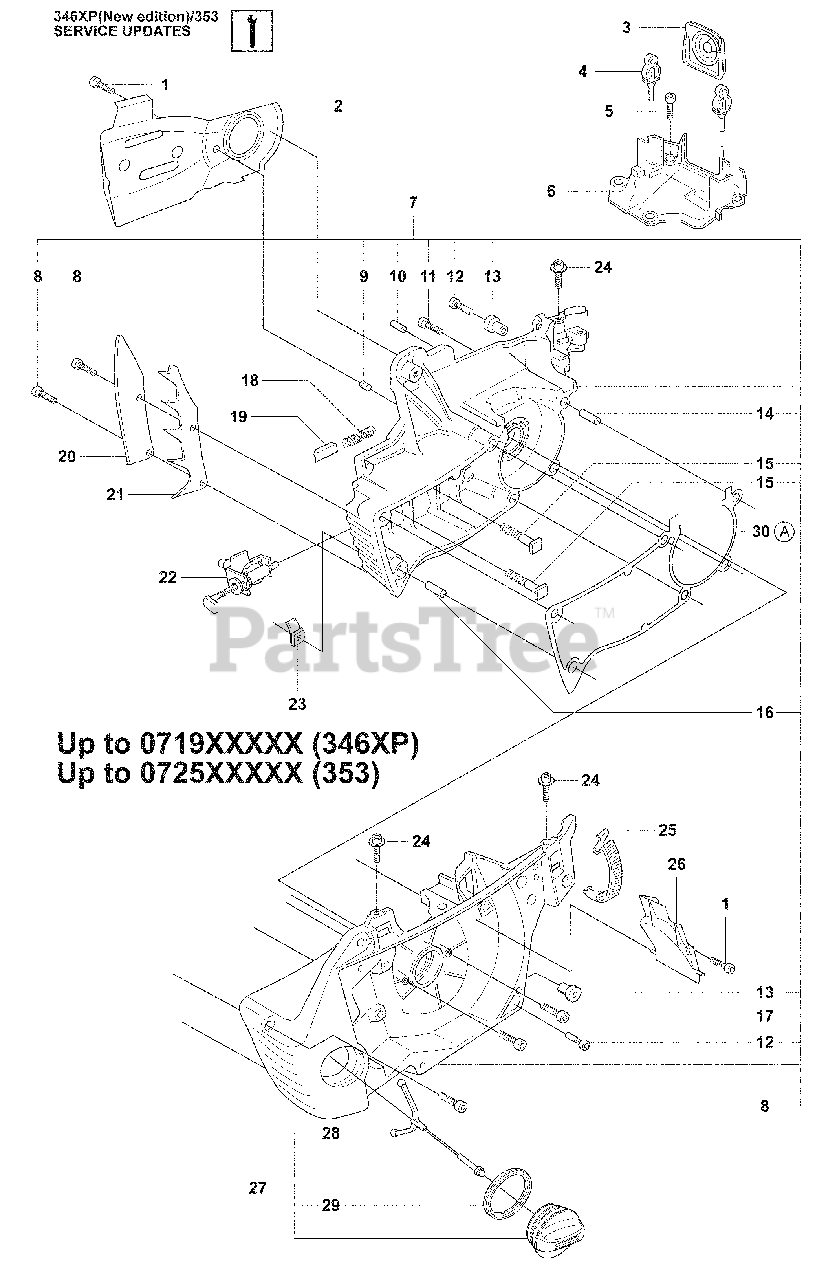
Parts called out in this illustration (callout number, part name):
7	CRANKCASE ASSY.
13	Movement Limiter
18	Lock Spring
21	Felling Dog
22	Chain Tensioner
23	Chain Catcher
25	Top Cover Buckle Clip, Orange
27	Oil Tank Cap, Grey
29	Oil Cap Gasket
30	Gasket Set
